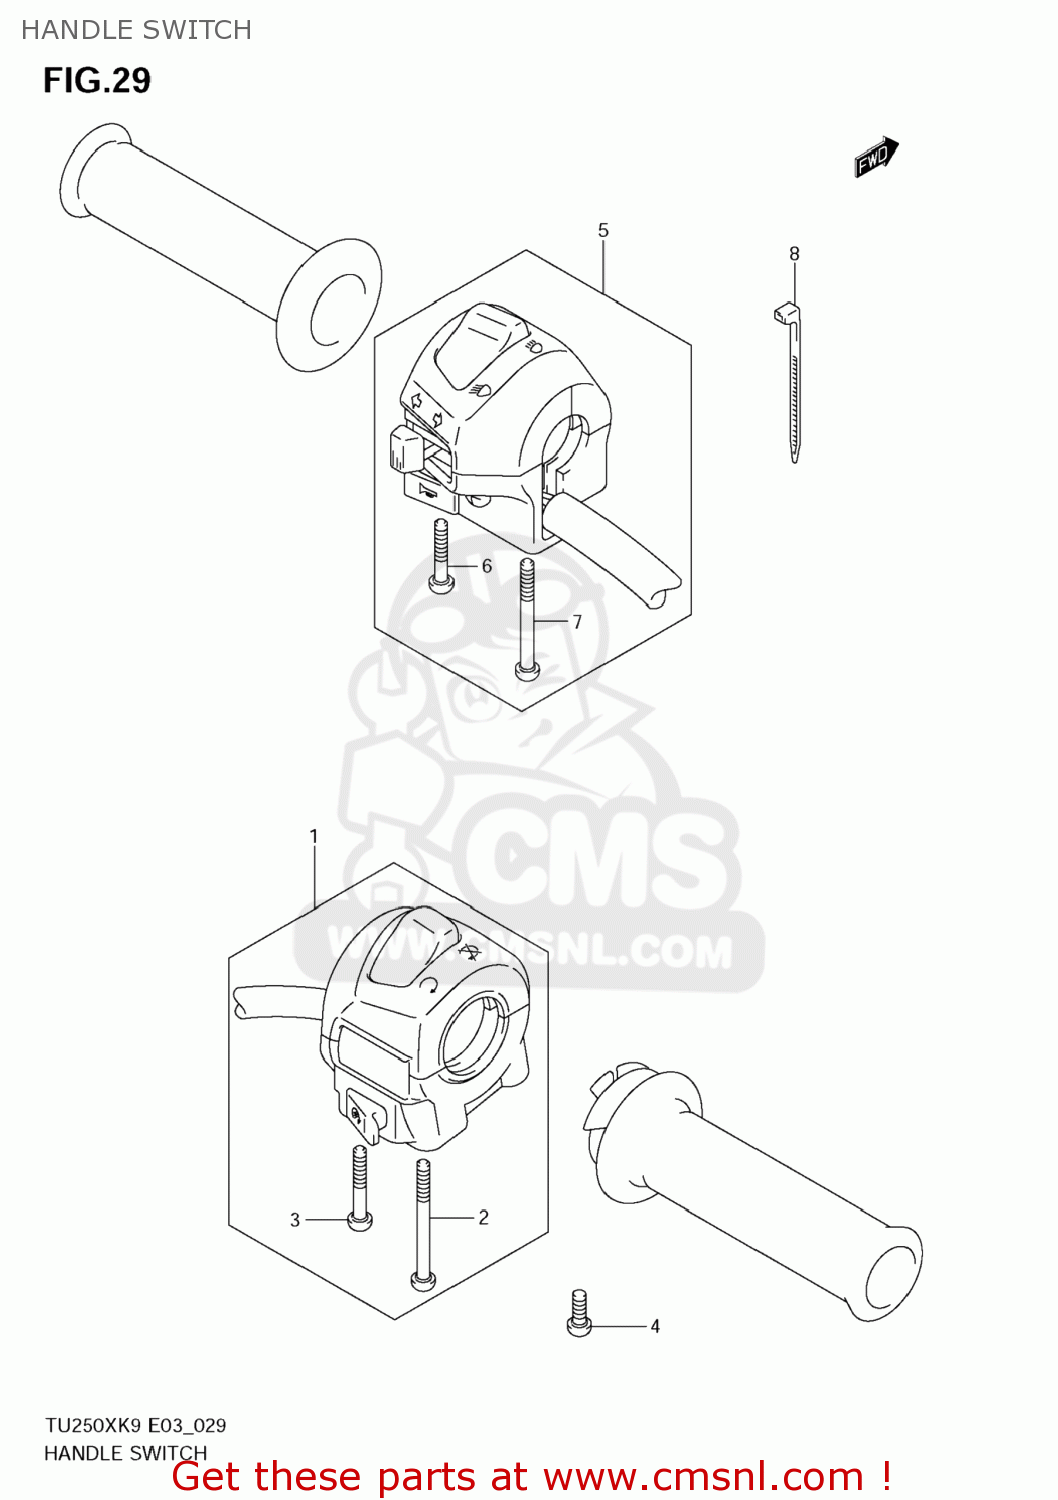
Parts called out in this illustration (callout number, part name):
1	SWITCH ASSY,HA
2	SCREW
3	SCREW
4	SCREW
5	SWITCH ASSY,HANDLE,L
6	SCREW
7	SCREW
8	CLAMP(L:145)
